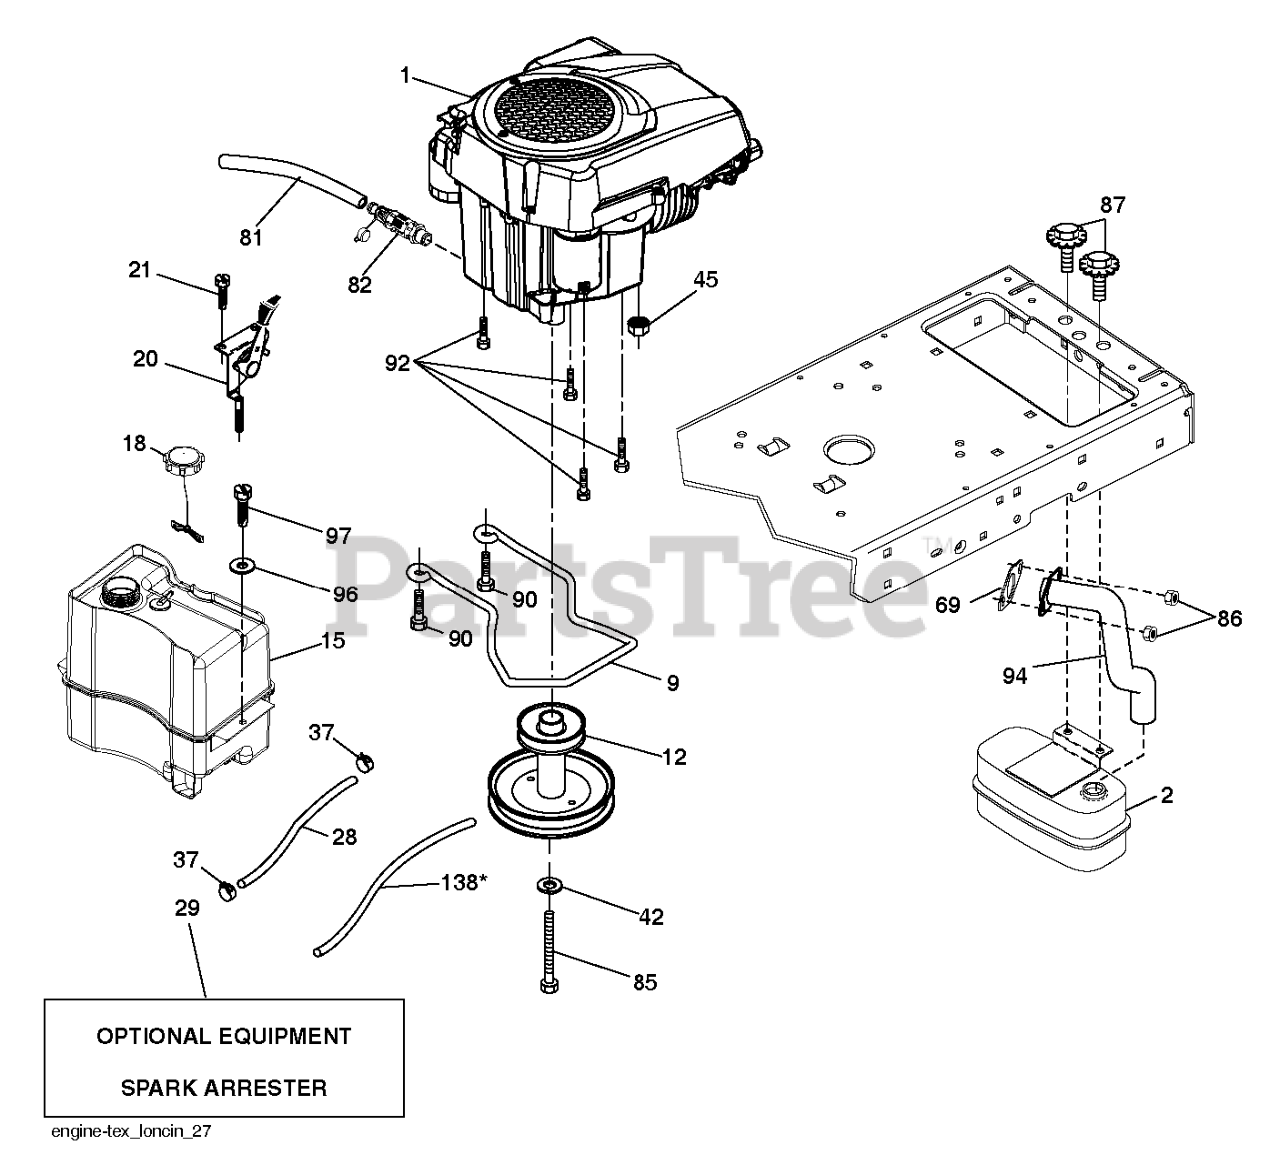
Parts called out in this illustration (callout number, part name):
1	ENGINE.LONCIN.SPARE./608
2	MUFFLER.ASM.SINGLE
9	KEEPER.BELT.ENG.4.25"2.BLT.431
12	ENGINE.PULLEY
15	FUEL.TANK.ASM.NON-EPA
15	Tanks
18	CAP ASM.FUEL.2.25"FR.
20	CONTROL.TH/CK.C.
28	LINE.FUEL.20
29	KIT.SPARK ARRESTOR 794945 B&S
37	HOSE CLAMP
45	NUT HEXAGON WITH FLANGE, SERRA
69	GASKET GASKET.EXHAUST. LONCIN
81	TUBE, DRAIN OIL ASM.
82	VALUE.OIL.DRAIN
85	BOLT.HEX.7/16-20X4.GR5.1.5BLUE
86	NUT.HEX.FLANGE.TOPLOCK
87	BOLT.5/16-18UNCX3/4 W/SEMS.BLK
90	SCREW 3/8-16X1
92	SCREW 3/8-16X1
94	TUBE TUBE.EXHAUST.LONCIN 608.T
97	SCREW HEXWSHR 1/4-20X3/4
